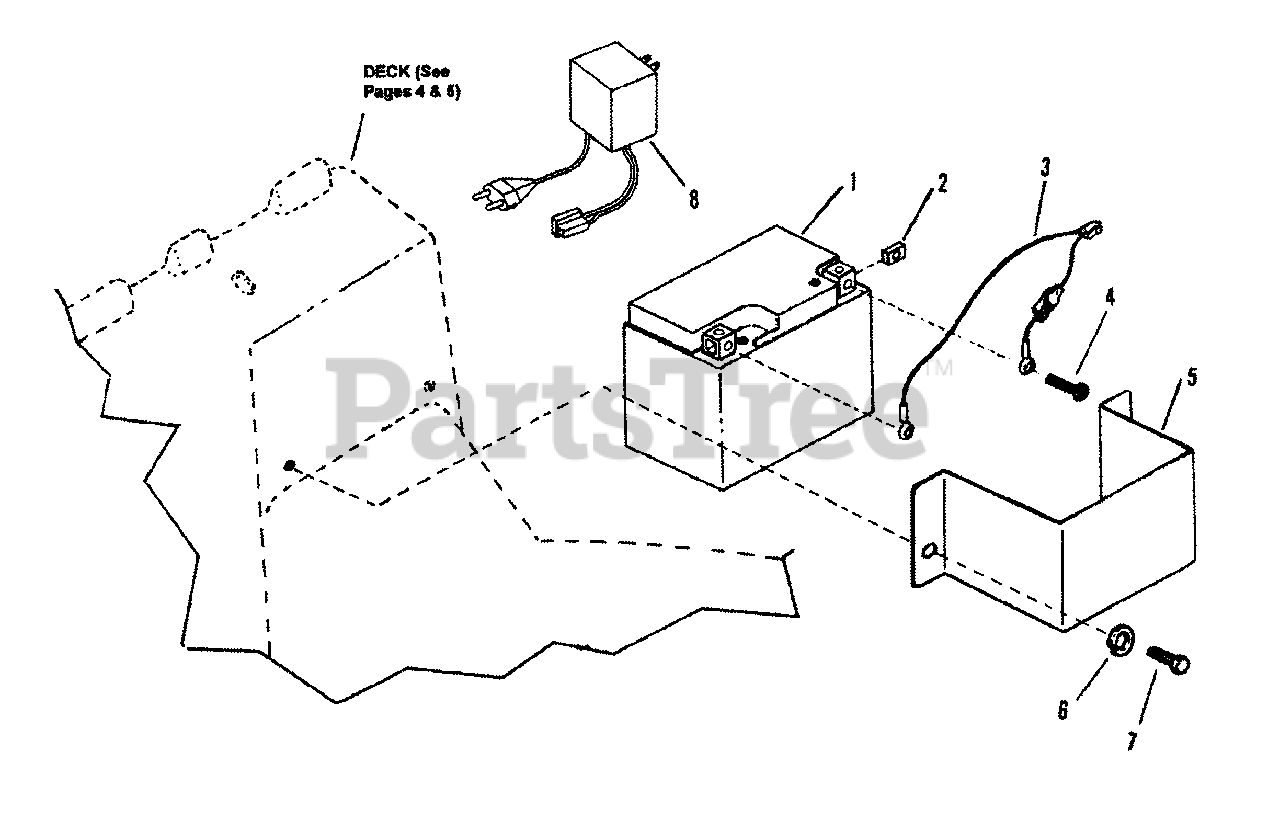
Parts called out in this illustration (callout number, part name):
1	BATTERY, 12 Volt
2	NUT, Battery Terminal
3	HARNESS, Battery
4	SCREW, M5 x 10mm Cross Recess Pan Head
5	BRACKET, Battery Support
6	WASHER, 1/4" Split Lock
7	SCREW, 1/4-20 x 3/4" Hex Head Cap, Grade 5
8	CHARGER, Battery
